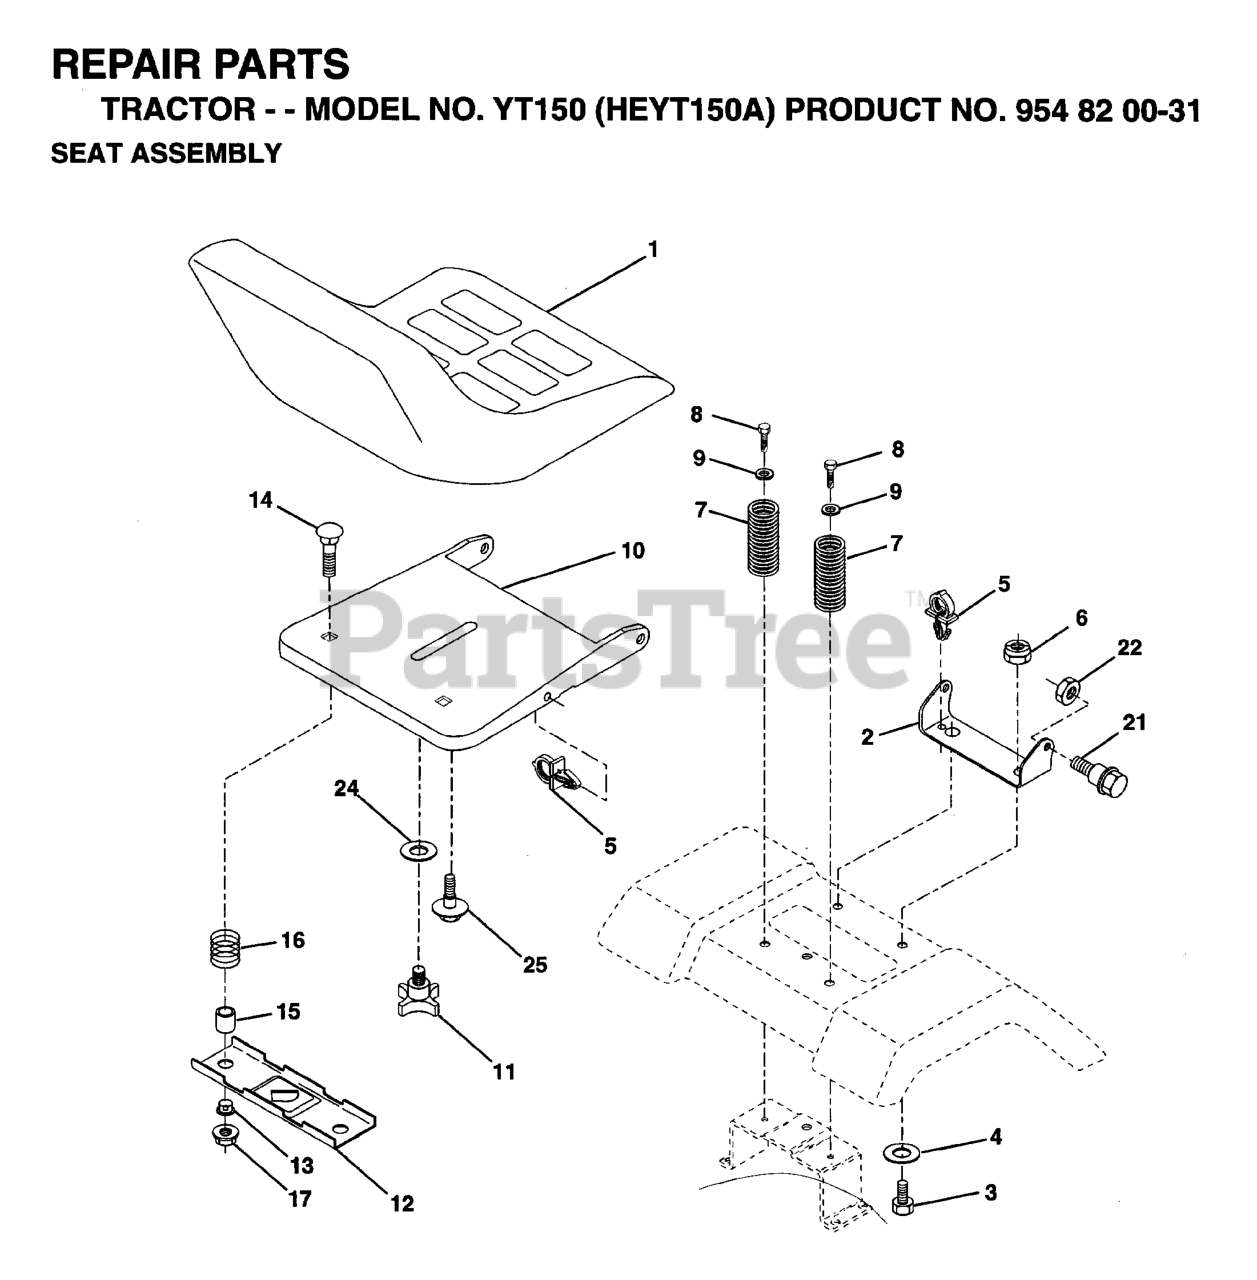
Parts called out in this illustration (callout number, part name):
1	SEAT, GRAY
2	SEAT PIVOT BRKT
3	BOLT
6	NUT
7	SPRING COMPRESSION
8	SCREW GTV
9	WASHER
10	SEAT PAN
11	KNOB 1/2" YT
12	BRKT SWITCH
14	Bolt Rdhd. Sht. Nk 1/4-20 x 1-3/8
15	SPACER SPLIT 28X.96
17	NUT T
21	BOLT.SHOULDER.5/16-18
22	NUT.71038.31-18.HEX.NYLOCK
25	BOLT,SHOULD
